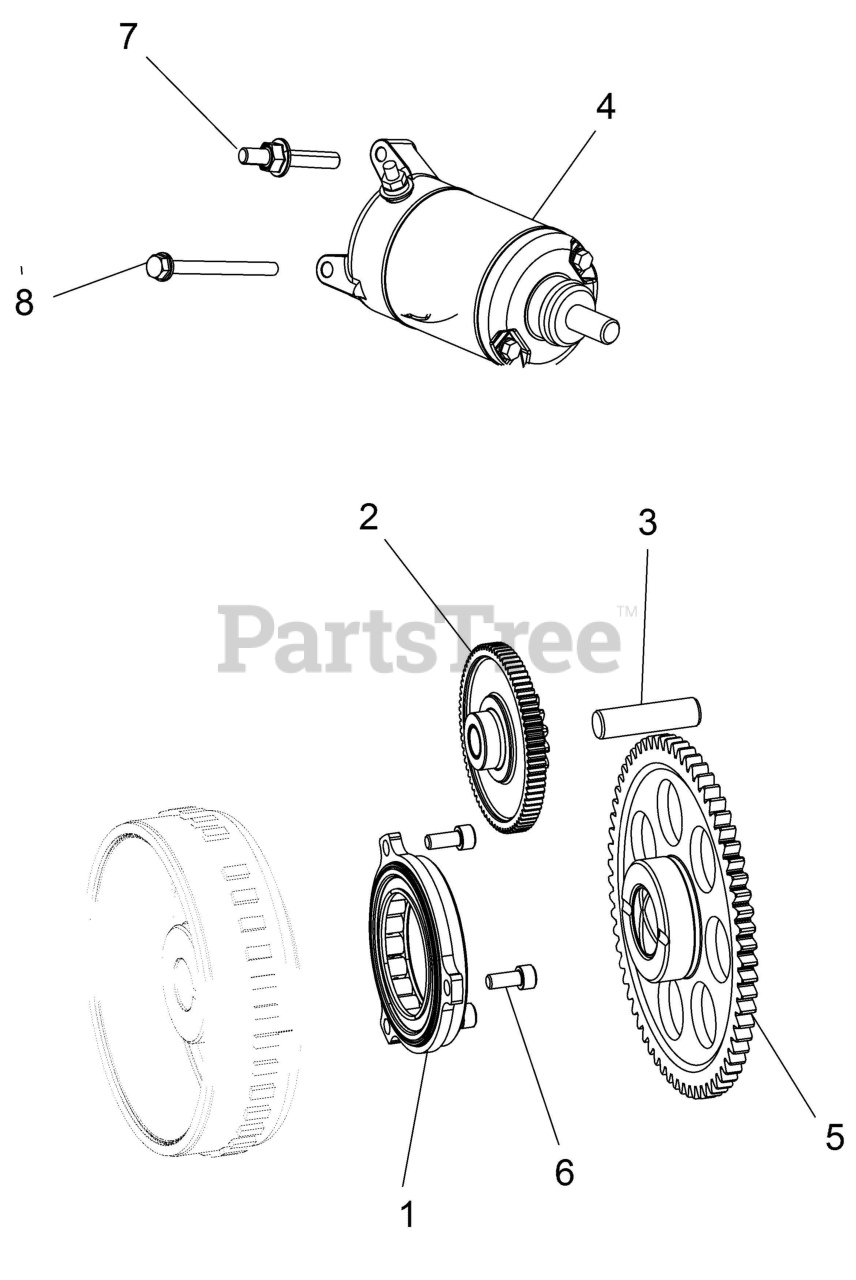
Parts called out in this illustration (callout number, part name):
1	ASM,SPRAG CLUTCH,HUB,STARTER
2	ASM-GEAR,STARTER
3	PIN-SOLID,STARTER TQ LIMITGEAR
4	STARTER, 1 CYLINDER
5	GEAR-FREEWHEEL,1WAY CLUTCH
7	STUD-DOUBLE,END,M6X1.0X25/10
